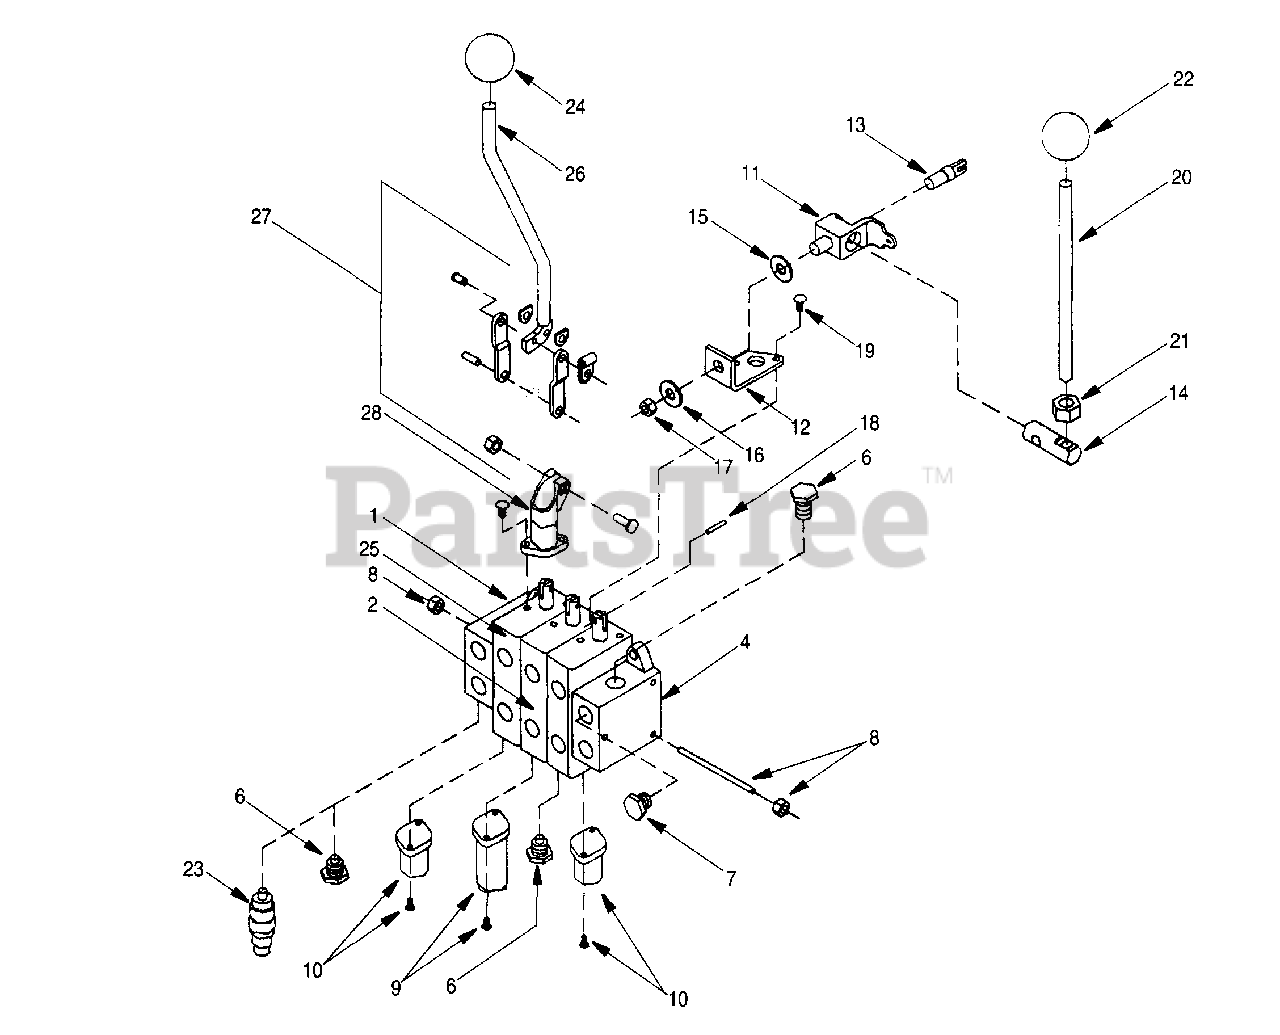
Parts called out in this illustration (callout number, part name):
1	Inlet Section Assembly
2	Spool Section Assembly, Boom
4	Outlet Section Assembly
6	Shut-off Plug
7	Plug, 7/8-14 O-Ring Boss
8	Tie Rod Kit, (2 Spool Section)
9	WM-Repair Kit, Float End
10	Repair Kit, Standard Section
11	Pivot Bracket
12	Mounting Bracket
13	Clevis End
14	Axle Valve Control
15	Pivot Bracket
16	Bell Washer
17	Jam Locknut, 1/2-20
19	Button Hd Cap Scrw, 1/4 UNC x 5/8
20	Straight Handle
21	Jam Nut, 1/2-UNC
23	Relief Valve Assembly, 2250 psi
25	Spool Section Assy, Aux.
26	Offset Handle
27	Handle Service Kit
28	Handle Bracket
